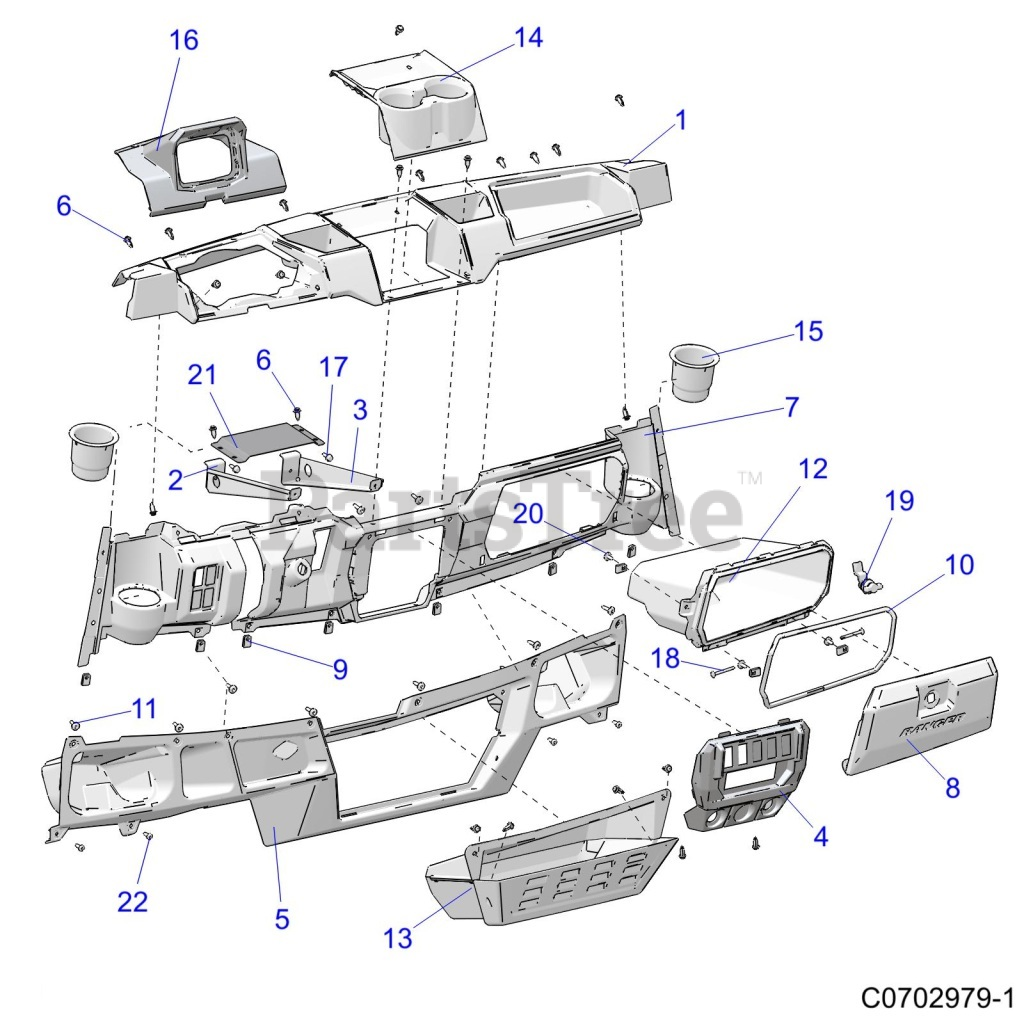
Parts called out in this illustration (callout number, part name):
1	DASH-UPPER,BLK
2	BRKT-DASH,LH
3	BRKT-DASH,RH
4	DASH-CONTROLS,BLK
5	DASH-STORAGE,BLK
6	RIVET-TUFLOK,.315-.325X.787 (5
7	DASH-MAIN,BLK
8	COVER-BOX,GLOVE,BLK
9	NUT-M6-1.0,U-TYPE (2.5-3.8)
10	SEAL-GLOVEBOX
11	SCR-TXTH-M6X1.0X25 RIE
12	BIN-GLOVEBOX,BLK
13	BIN-LOWER,STORAGE,BLK
14	DASH-CENTER TRAY,BLK
15	HOLDER-CUP
16	DASH-GAUGE BEZEL,BLK
17	SCR-M6X1.0X20,HXHD,FLG,TDFM,BL
18	PIN-HINGE,GLOVEBOX
19	LATCH-1/4 TURN,CAM
20	SCR-M6X1X16 TR/TX-M
21	BRKT-DRIP PLATE
22	SCR-TX TRUSS-#14X3/4,HI/LO ZBK
